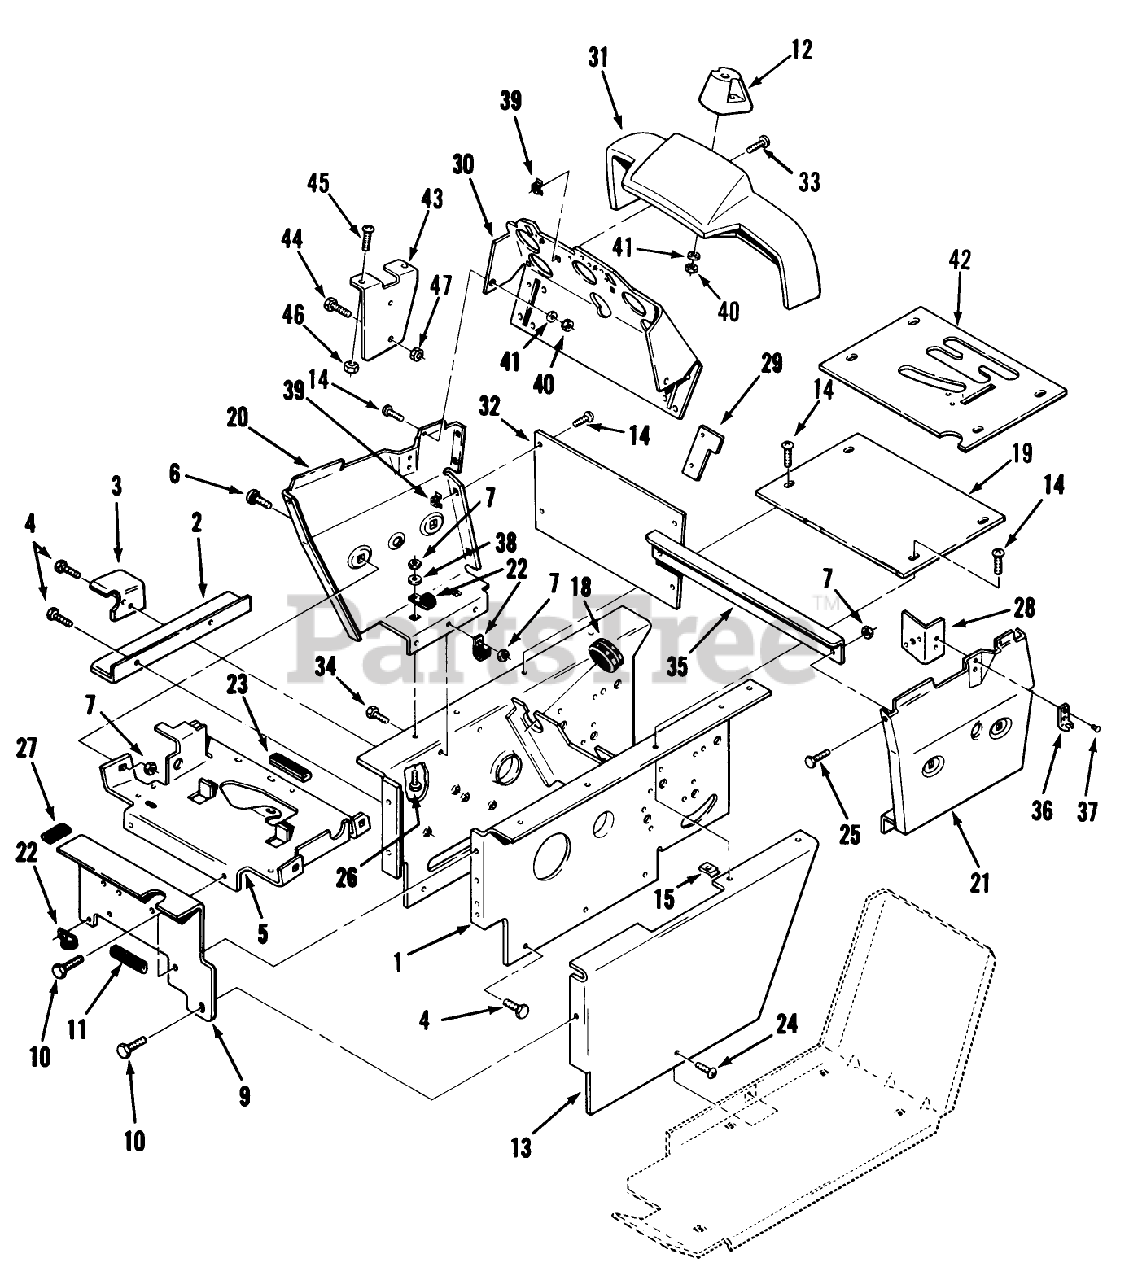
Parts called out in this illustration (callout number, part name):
2	ANGLE-BELT GUARD *B
4	SCREW
5	WLD-SUPPORT*B
10	SCREW
12	COVER-STEERING SHAFT
13	COVER-L.H. *R
14	SCREW-PPH
18	GROMMET
22	CLIP
26	CARRIAGE BOLT -4
28	BRACKET-SWITCH SU
29	STOP-CHOKE
35	STIFFENER-PANEL
36	KEEPER-LATCH
37	RIVET
38	WASHER 5/16 SAE
